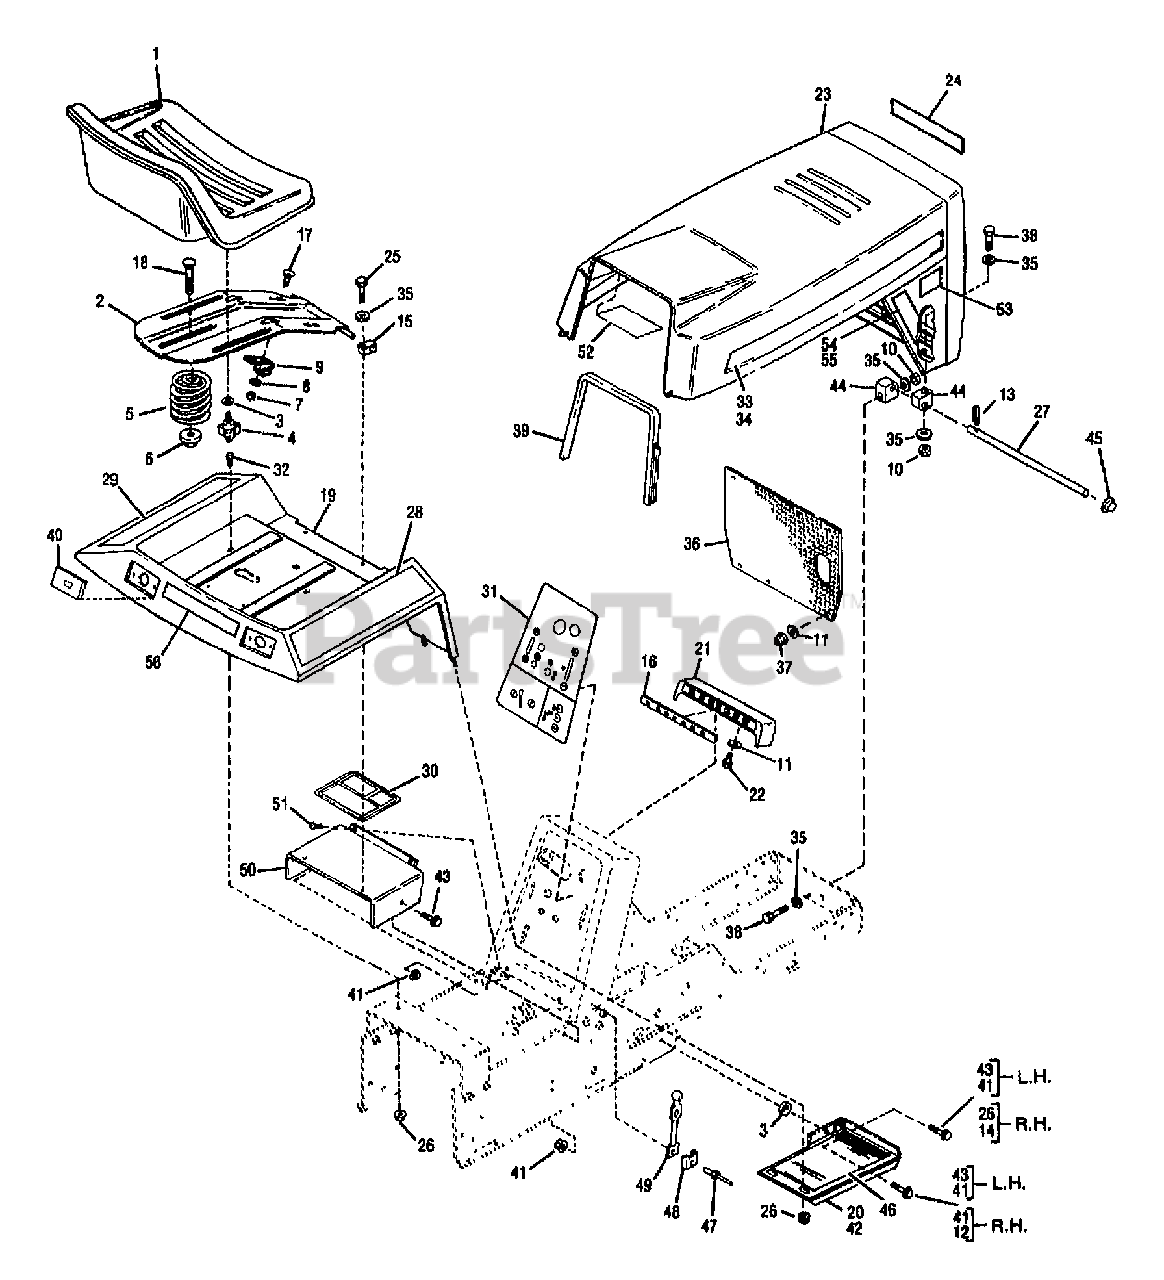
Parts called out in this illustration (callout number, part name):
2	SUPPORT-SEAT
3	WASHER-.986X.437X.083 ZP
5	SPRING
6	NUT & WASHER
7	NUT-HEX 1/4-20 ZP
8	WASHER-LK .25 ZP
9	BRACKET-ACTUATOR
10	NUT-H/LK 5/16-18
11	WASHER-.219 ZP
12	SCR-HH 3/8-16X1.0 G5 ZP
13	PIN-COTTER .093X.50 ZP
14	SCR-5/16-18X1.00
15	BLOCK-SWIVEL
17	BOLT-CARR 1/4-20X1/2
18	BOLT-CARR .375-16X1.25
19	ASSM-FENDER
20	FOOTREST-RH
21	HSG-LIGHT CLUSTER
22	SCR-SELF THD 10-16X1/2
23	HOOD AND GRILLE
24	DECAL-GRILLE
25	SCR-HFLK 5/16-18X1.25 ZP
26	NUT-HFLK 5/16-18 ZP
27	ROD-PIVOT
28	DECAL-FENDER RH
29	DECAL-FENDER LH
30	DECAL-INSTR
31	DECAL-INSTRUCTION
32	SCR-HFLK 5/16-18X.75 ZP
33	DECAL-HOOD LH
34	DECAL-HOOD RH
35	WASHER-FLAT 5/16 SAE
36	SCREEN-GRILLE
37	NUT-HFLK
38	SCR-HH 5/16-18X1.5 G5 ZP
40	REFLECTOR
41	NUT-HFLK 3/8-16 ZP
42	FOOTREST-LH
44	PIVOT
45	NUT-PUSH
46	PAD-FOOT REST
47	RIVET-POP 3/16X1/2
49	LATCH-RUBBER
50	TUNNEL ASSY.
51	SCR-THRD FRM 5/16-18X5/8
52	DECAL-SVC INST
53	DECAL-HYDRO
54	DECAL-SIDE PANEL RH
55	DECAL-SIDE PANEL LH
56	DECAL-LOGO
